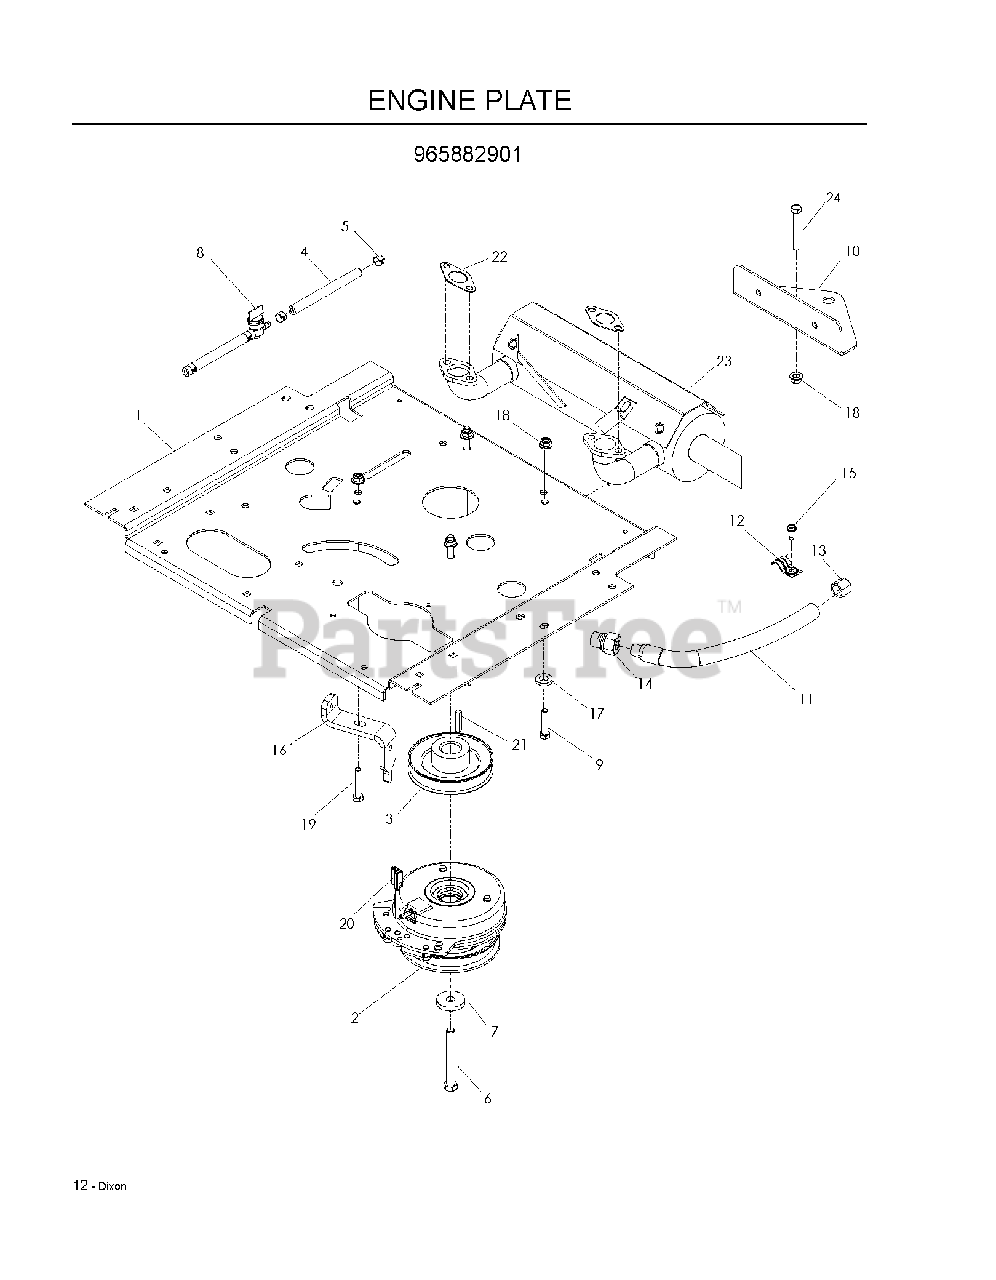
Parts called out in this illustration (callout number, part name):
1	PLATE, ENGINE, BLACK
2	CLUTCH, ELECTRIC
4	FUEL LINE 5"
5	HOSE CLAMP
6	HCS 7/16-20X3-1/2 GR 5 ZN
7	CLUTCH, WASHER
8	FUEL VALVE
9	CAPSCREW 5/16 X 1/1/2 HEX HEAD
10	HITCH, BLACK
11	OIL DRAIN HOSE
13	DRAIN CAP
14	ADAPTER, OIL DRAIN
15	SCREW 1/4 X 5/8
16	STOP, CLUTCH BLK
17	FLAT WASHER 5/16 SAE
18	5/16-18 NYLOC FLANGE NUT
19	HCS 5/16C X 1 3/4
20	CLUTCH HARNESS
21	KEY, 1/4 SQ X 1 1/4
22	EXHAUST GASKET - KAW
23	MUFFLER
24	BOLT 5/16C X 2 1/2
